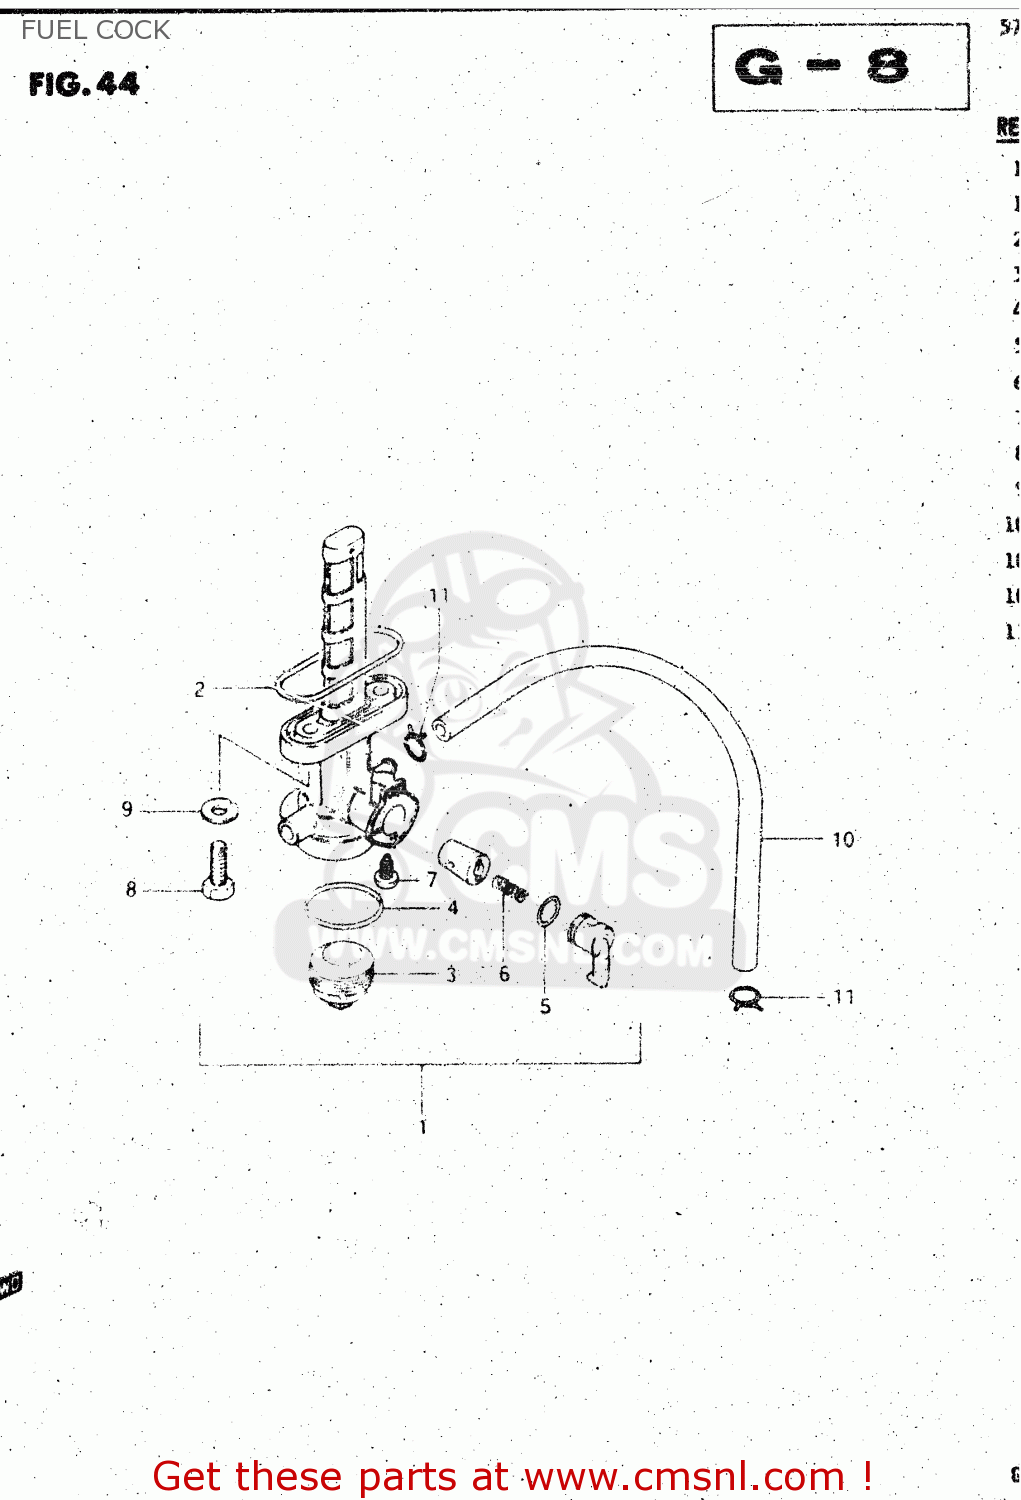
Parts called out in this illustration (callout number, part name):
1	COCK ASSEMBLY,FUEL
2	O RING,FUEL COCK
3	CUP,STRAINER
4	GASKET,FILTER (NAS)
5	O-RING,LEVER
6	SPRING
7	SCREW
8	BOLT(6X20)
9	GASKET(6.4X11.5X0.8) (NAS)
10	HOSE
11	CLIP
